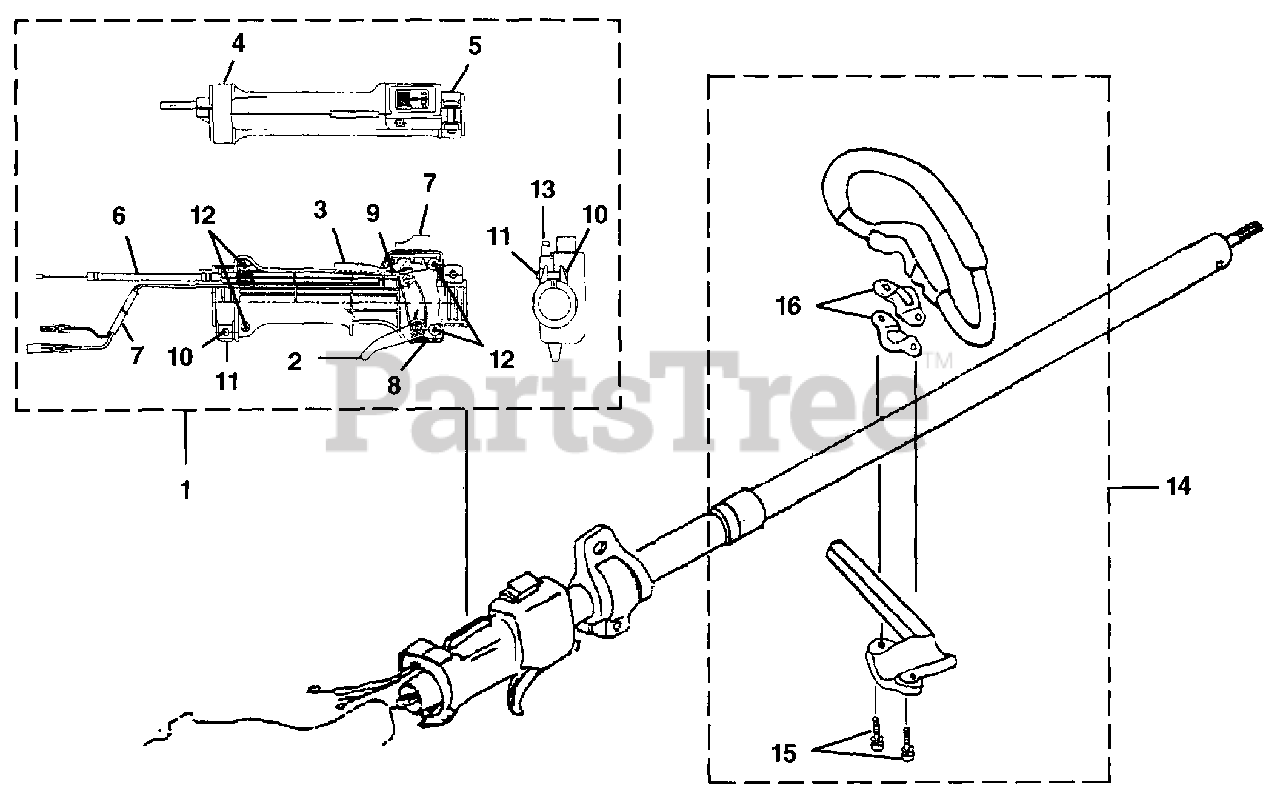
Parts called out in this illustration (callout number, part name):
1	CONTROL LEVER ASSEMBLY
2	THROTTLE-Trigger
3	LATCH-Trigger
6	CABLE- Throttle
7	SWITCH ASSEMBLY
12	SCREW-Tapping
13	LOCK-Throttle Start
14	HANDLE ASSEMBLY
15	BOLT-Socket Head (M6 x 45)
16	CLAMP-Handle Bar
